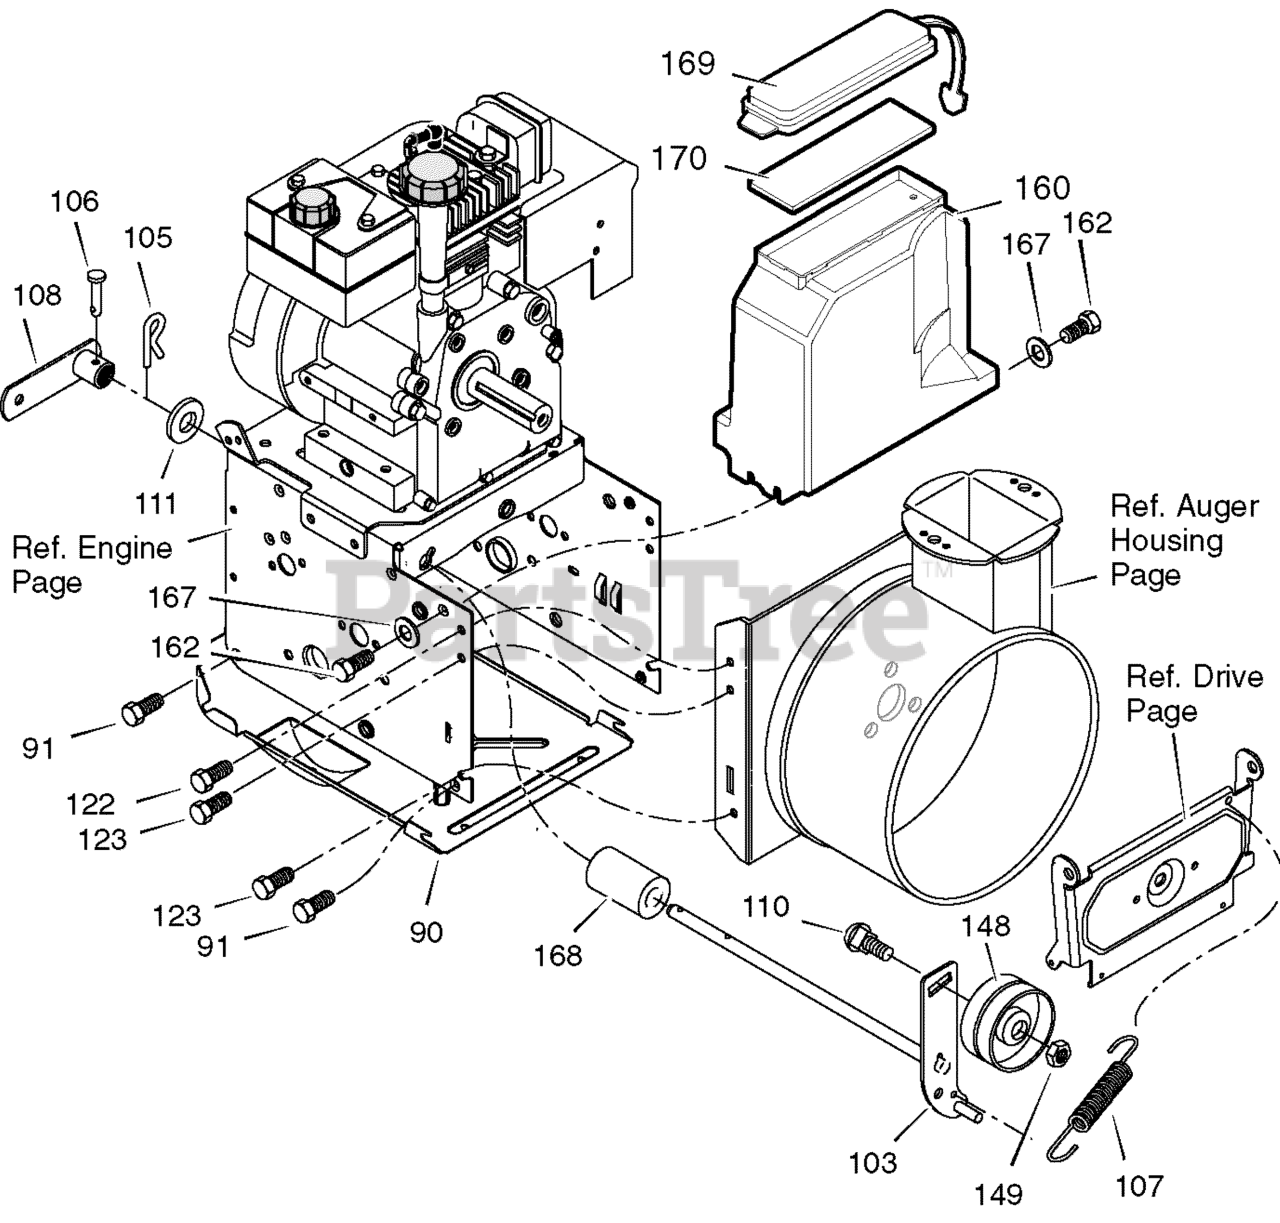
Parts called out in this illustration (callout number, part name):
90	COVER, BOTTOM
91	SCREW
103	YZ IDLER, AUGER
105	PIN, HAIR
106	PIN, CLEVIS
107	SPRING, TENSION
108	YZ SPRING ATTACH
110	BOLT, CARR.
111	WASHER, FLAT
122	SCREW, TAP
123	SCREW, TAP
148	PULLEY, IDLER
149	NUT, JAM 3/8-16
160	COVER, BELT
162	SCREW, TAP
167	WASHER, FLAT
168	SPACER
169	LID, TOOL BOX
170	PAD, FOAM
